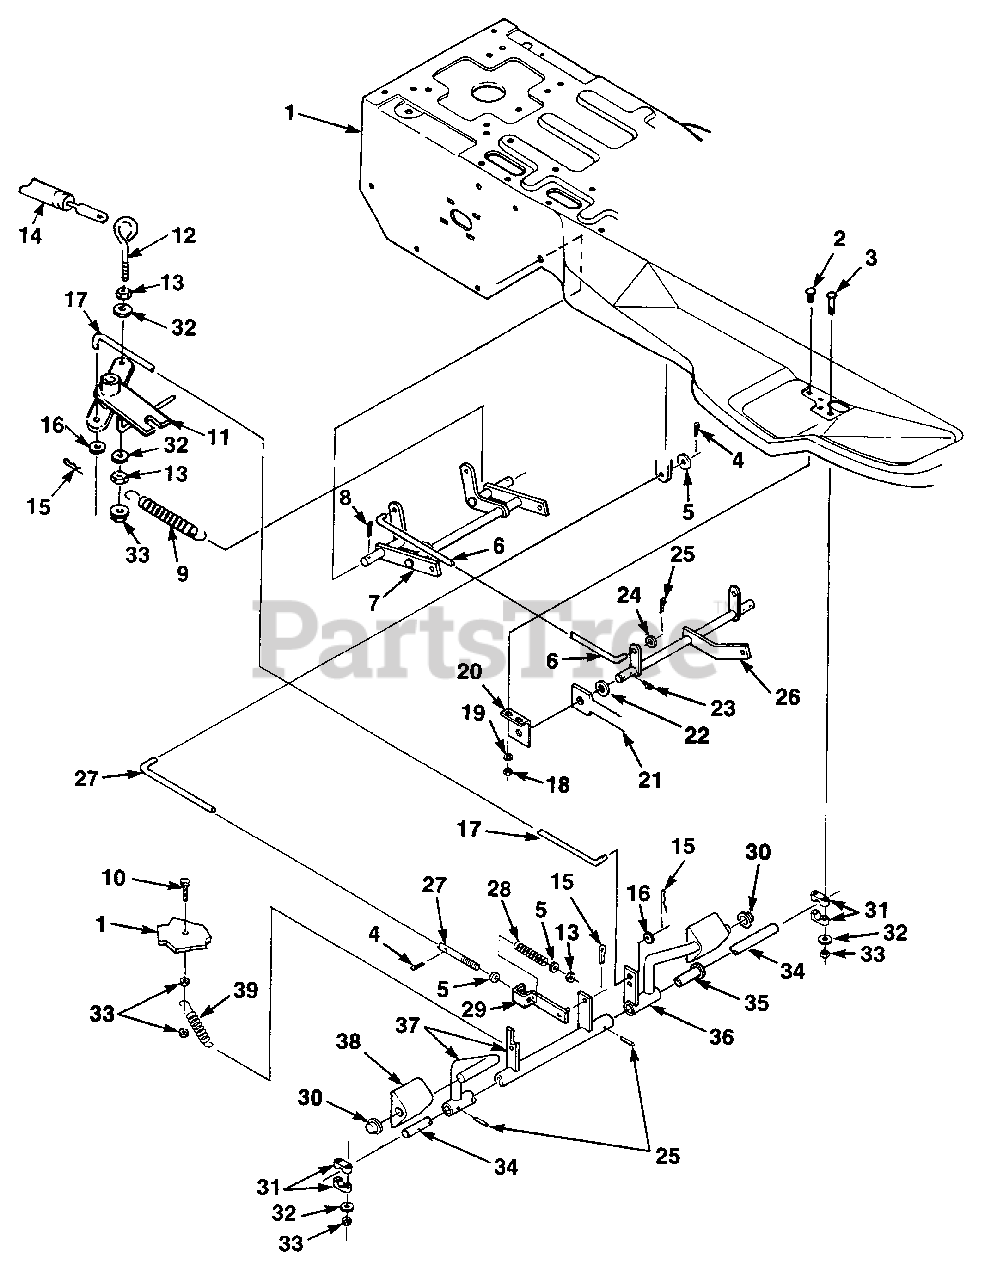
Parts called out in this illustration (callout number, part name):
2	BOLT- Carr 1/4-20 x 5/8
3	BOLT- 1/4-20 x 1 1/2
4	PIN- Cotter
5	WASHER (5/16 Plain)
6	ROD- Deck lift
7	BRACKET- Rear hanger
8	PIN- Cotter
9	SPRING- Extension
10	SCREW- 1/4-20 x .625
11	ARM- Pivot
12	BOLT- Eye
13	NUT- (Lead 1/4-20)
15	PIN- Cotter
16	WASHER- 1/4
17	ROD- Clutch
18	NUT- 1/4-20
19	WASHER- Lock 1/4
21	SUPPORT- Front axle
22	WASHER- (Flat 7/16)
23	PIN- Cotter
24	WASHER- Plain (flat 7/16)
25	PIN- Cotter
26	HANGER- Front
27	ROD- Brake
28	SPRING- Brake
29	BRACKET- Brake spring
30	NUT- Push
32	WASHER- Flat 1/4 reg
33	NUT- Centerlock hex- 1/4-20
34	PEDAL SHAFT
36	PEDAL- Clutch
37	PEDAL- Brake
38	PEDAL- Rubber
